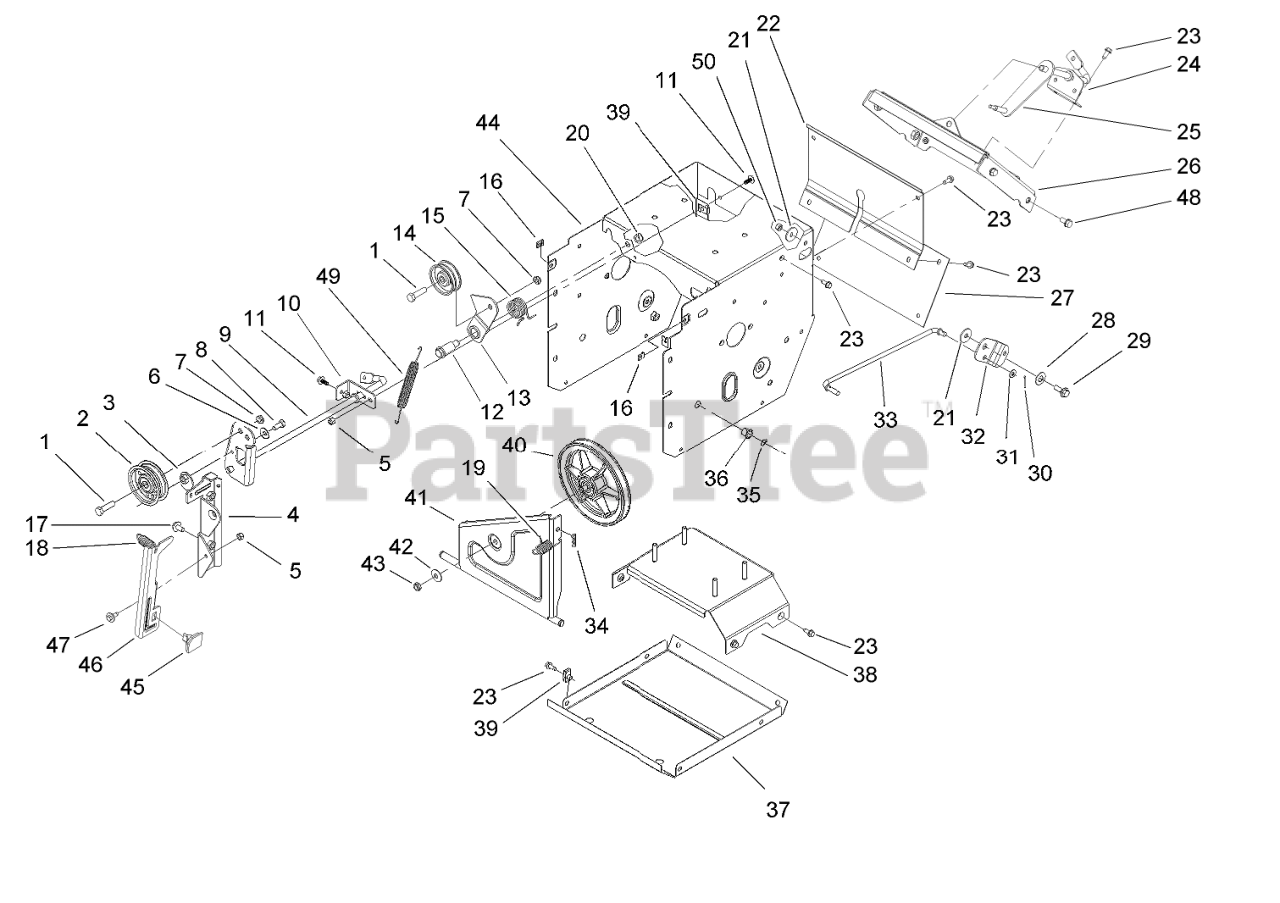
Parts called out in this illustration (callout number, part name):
1	SCREW-HH
2	PULLEY-IDLER
4	BRACKET-IDLER, IMPELLER
5	NUT-LOCK, NI
6	WASHER-BELLEVILLE
7	NUT-LOCK, NI
8	SCREW-HH
9	IMPELLER CLUTCH ASM
10	BRACKET-REAR, CLUTCH
11	SCREW-HHF
12	BOLT-SHOULDER
13	ARM-IDLER, TRACTION
14	PULLEY-IDLER
15	SPRING-TORSION
16	NUT-SPEED, U-TYPE
17	SCREW-HHF
18	SPRING-EXTENSION
19	SPRING-EXTENSION
20	NUT-LOCK, NI
21	WASHER-PIVOT
22	COVER-UPPER
23	SCREW-HWH
24	BRACKET-ROD, SHIFT
25	LEVER-CONTROL, TRACTION
26	SHIFT PLATE ASM
27	COVER-LOWER
28	WASHER
29	SCREW-SHOULDER
30	PIN-COTTER
31	WASHER-PLAIN
32	BELLCRANK-DRIVE
33	LINK-CONTROL, SPEED
34	PIN-COTTER
35	RING-RETAINING
36	BUSHING-NYLINER
37	PAN-BOTTOM
38	BRACE FRAME ASM
40	PULLEY-TRACTION
41	PULLEY PIVOT ASM
42	WASHER-BELLEVILLE
43	NUT-HEX
44	TRACTION FRAME ASM
45	PAD-BRAKE
46	ARM-BRAKE
47	SCREW-SHOULDER
48	SCREW-HWHTF
49	SPRING-EXTENSION
50	NUT-LOCK, NI
